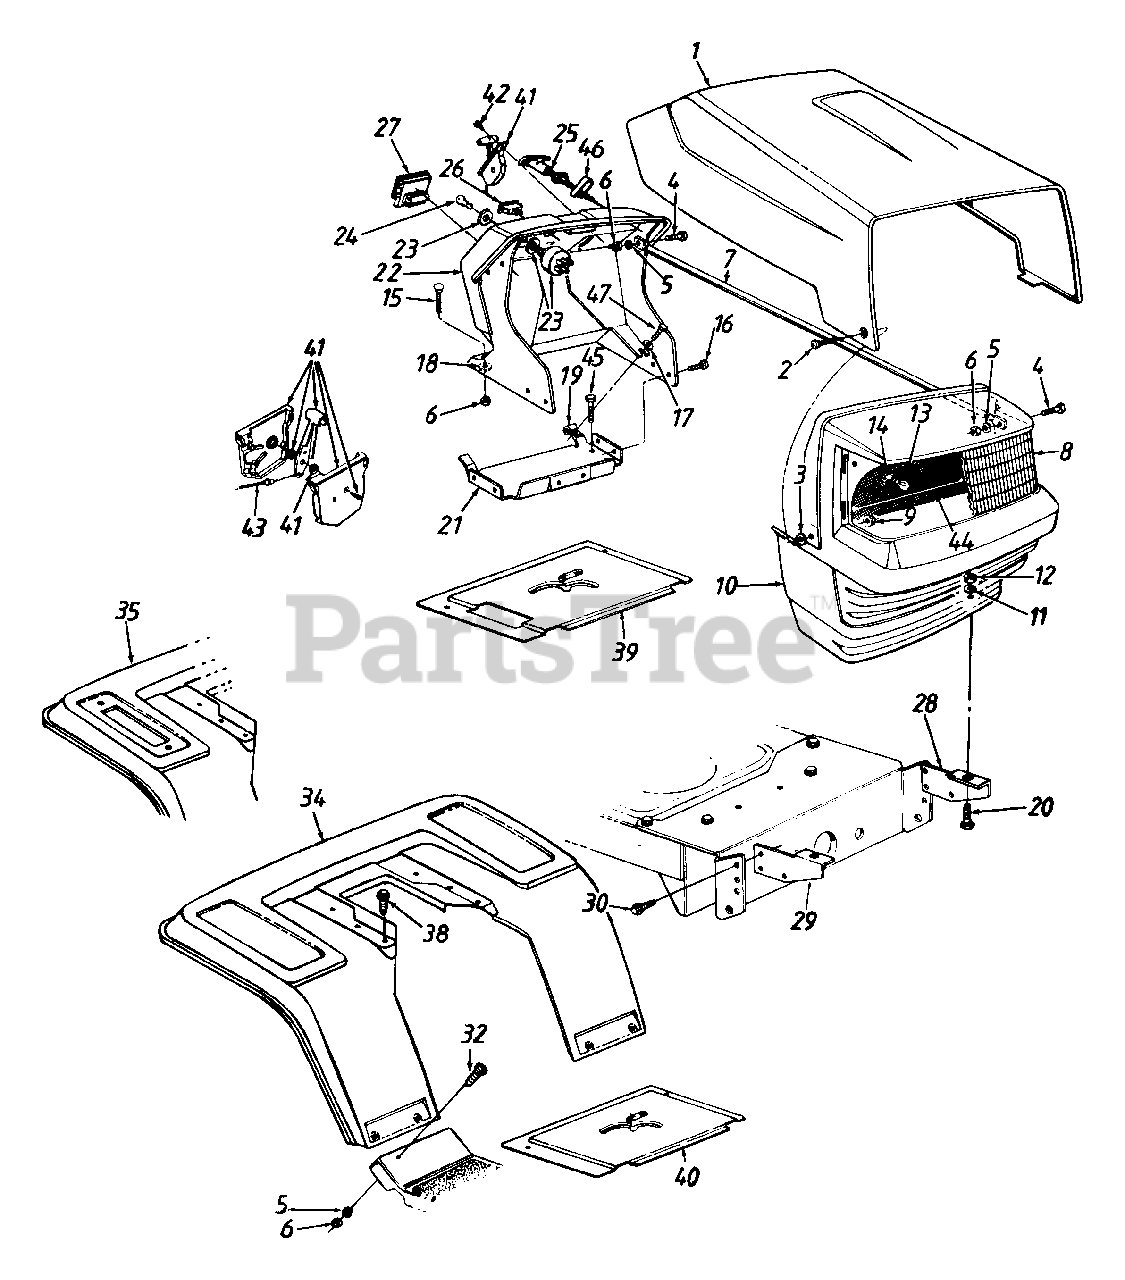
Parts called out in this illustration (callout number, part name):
3	Fl-Wash. .28" I.D. x .75" O.D.
4	Hex Bolt 1/4-20 x .62" Lg.
5	L-Wash. 1/4" I.D.
6	Hex Nut 1/4-20 Thd.
8	Headlight Lens
9	Flange L-Nut 1/4-28 Thd.
10	Grille
11	Fl-Wash. .344" I.D. x 1" O.D.
12	Hex Nut 5/16-18 Thd.
13	Lamp
14	Socket
15	Carriage Bolt 1/4-20 x .75" L g.
16	Hex Wash. Hd. TT-Tap Scr. 1/4-20 x .5" Lg.
17	Fl-Wash. .281" I.D. x.73" O.D.
18	Bolt Retainer 1/4" I.D.
19	Speed Nut 1/4-20 Thd.
20	Hex Bolt 5/16-18 x .75" Lg.
23	Ignition Switch
24	Ignition Key
25	Choke Control
26	Light Switch
27	Ammeter
28	Grille Mtg. Brkt.- L H.
32	Truss Mach. Scr. 1/4-20 x 5" Lg.
41	Throttle Box Ass'y.
42	Truss Mach. AB-Tap Scr. #10 x .5" Lg.
43	Throttle Control Wire
44	Grille Reflector Label
45	Hex Wash. Hd. B-Tap Scr 5/16-18 x .5" Lg.
46	Choke Retainer
47	Hex TT-Tap Scr. 1/4-20 x .75" Lg.
